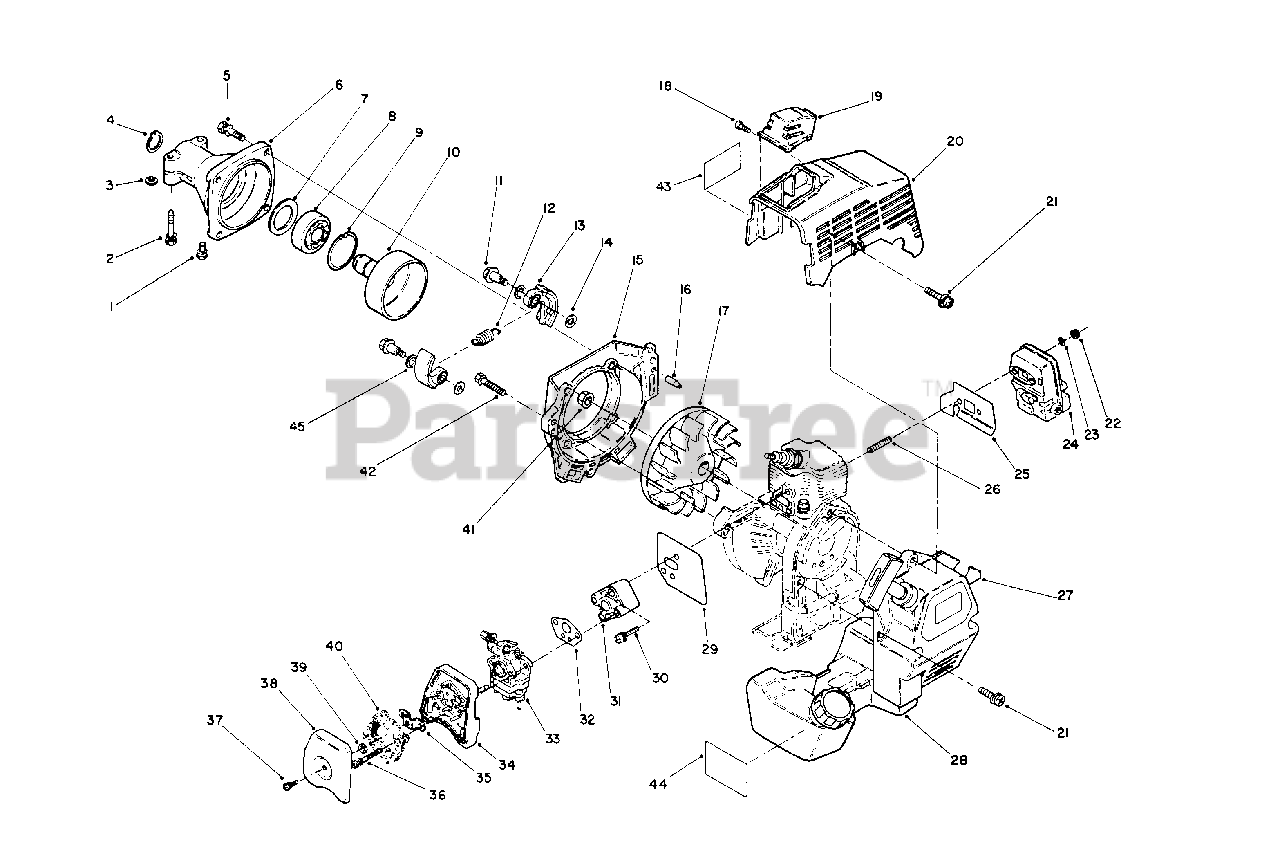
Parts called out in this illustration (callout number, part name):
1	Screw/Washer
2	Bolt/Washer
4	Ring-Retaining
5	Bolt/Washer
6	Case-Clutch
8	Bearing-Ball
9	Ring-Retaining
10	Drum-Clutch
11	Bolt-Clutch
12	Spring
13	Flyweight
15	Case-Fan
16	Pin-Dowel
17	Fan
19	Guard-Spark Plug
20	Cover-Engine
21	Screw/Washer
22	Nut-Flange Lock
24	Muffler Assembly
25	Gasket-Muffler
27	Recoil Assembly
28	Tank Assembly-Fuel
29	Gasket-Insulator
30	Screw/Washer
31	Insulator
32	Gasket-Carburetor
33	Carburetor Assembly
34	Case-Air Cleaner
36	Screw/Washer
37	Screw/Washer
38	Cover-Air Cleaner
40	Element-Air Cleaner
41	Nut-Conical
42	Screw-Pan Hd.
43	Decal-Hot
44	Decal-Fuel Mix
45	Washer-Wave
